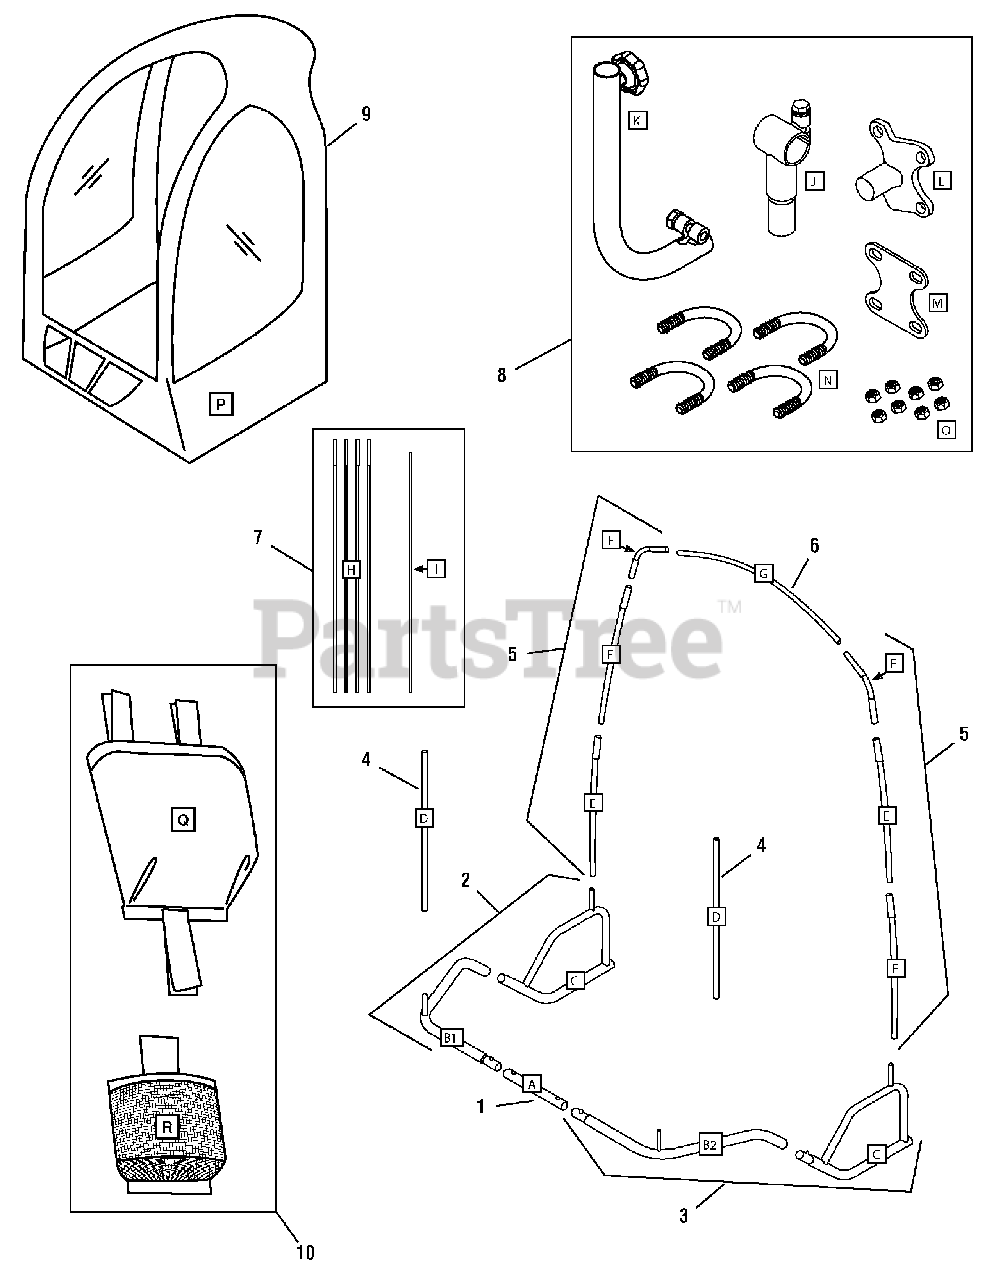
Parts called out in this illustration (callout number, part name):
1	BAR, Center Mounting
2	BAR, Side Mounting, R.H.
3	BAR, Side Mounting, L.H.
4	POLE, Front
5	POLE, Back Hoop Side & Corner, R.H. & L.H.
6	POLE, Back Hoop, Top
7	POLE, Front Hoop Side & Top
8	POST & MOUNTING HARDWARE, Upper & Lower
9	CAB, Fabric Shell
10	POCKET, Removable, Sand & Salt Opener
